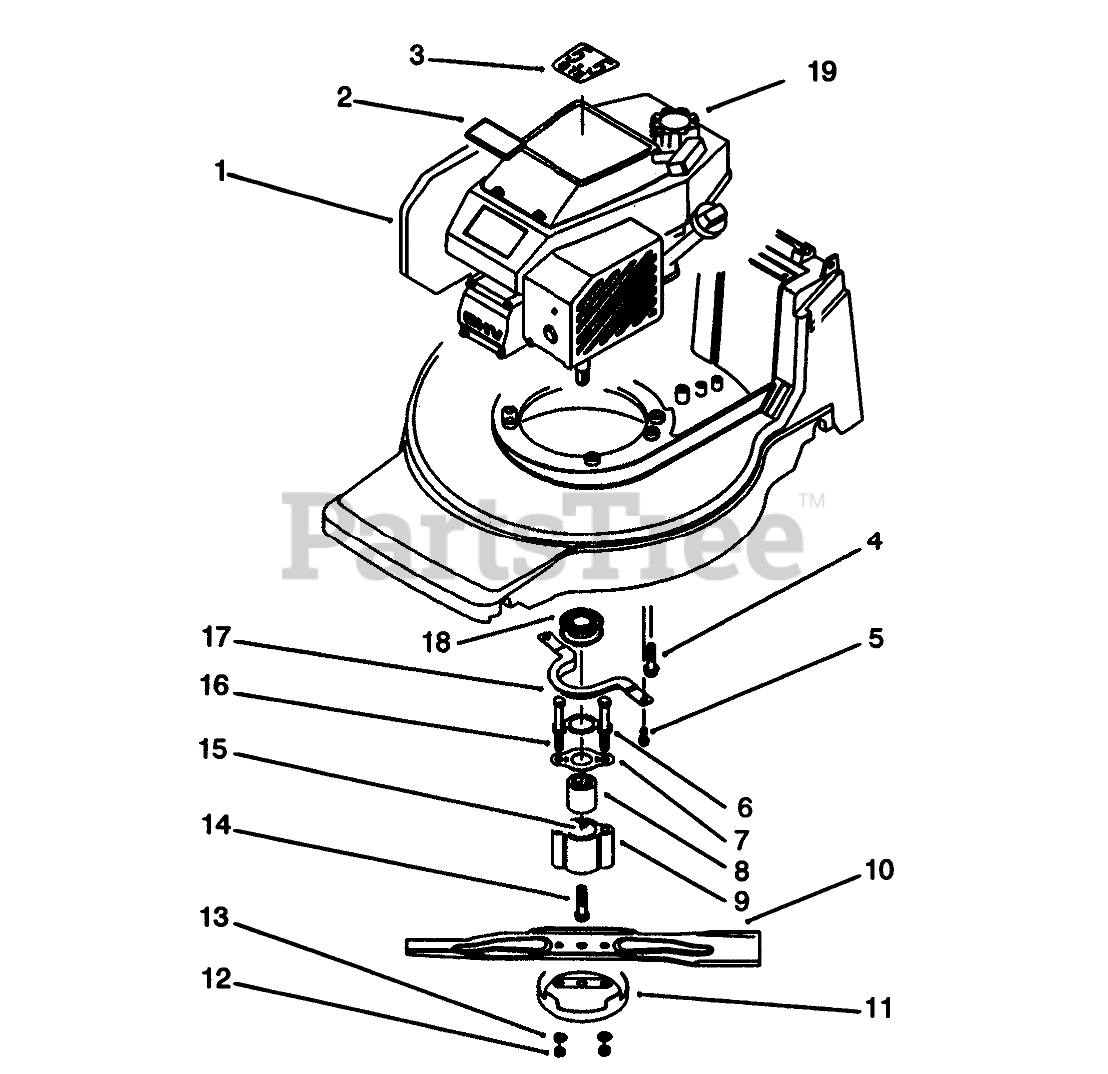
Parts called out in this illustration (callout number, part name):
1	ENG ASM-GTS150 KEY/NC
2	TORO LOGO PLATE
3	DECAL - ENGINE
4	SCREW-HWHTF
5	SCREW-HWH
6	BLADE RETAINER BRKT
7	SPRING FRICTION
9	RETAINER
10	Blade-48cm
11	CUP-SCALP, ANTI
12	NUT-LOCK
13	WASHER
14	SCREW - CRANKSHAFT
15	WASHER-LOCK
16	SCREW - BLADE
17	Guide-Belt
18	PULLEY-DRIVE, ZONE START
19	GAS CAP ASM
